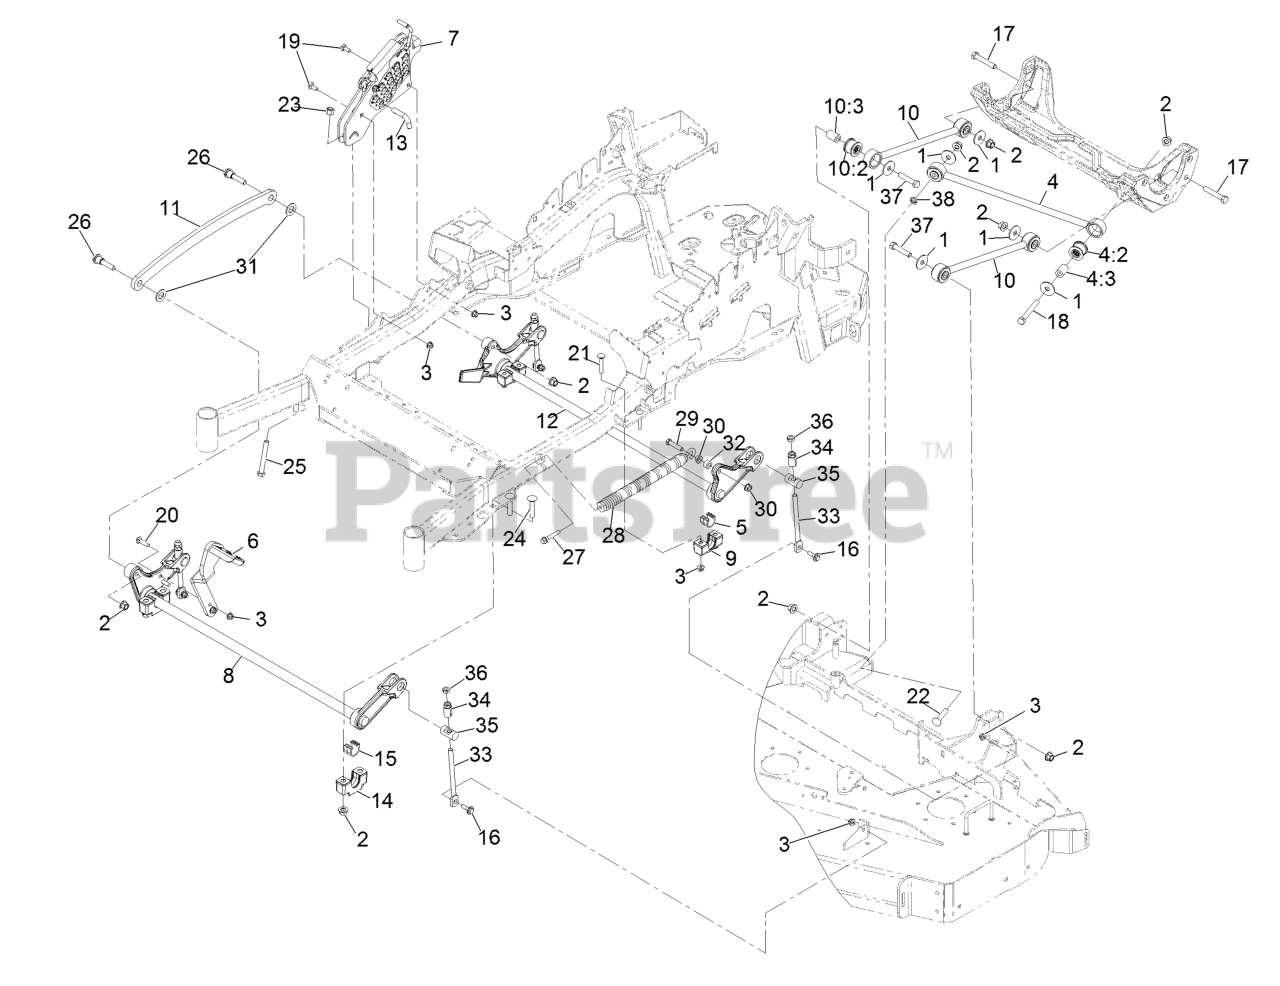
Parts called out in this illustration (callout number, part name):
2	Nut-Lock 1/2-13
3	Nut-Nyloc 3/8-16 Flg
4	Panhard Rod ASM
4:2	Bushing-Suspension, Rubber
5	Bearing-Cross Shaft, Rear
6	Lever-Foot
7	HOC ASM
8	Decklift-Front
9	Support-Cross Shaft, Bearing Rear
10	Deck Strut ASM
10:2	Bushing-Suspension, Rubber
11	Link-Lift, Deck
12	Lift-Deck, Rear
13	Pin-HOC
14	Support-Cross Shaft, Bearing
15	Bearing-Cross Shaft, Front
16	Screw-Hex Flange 3/8-16 X .80
17	Screw-HH 1/2-13 X 3
18	Screw-HH 1/2-13 X 4
19	Bolt-Carriage 3/8-16 X 1
20	Bolt-Carriage 3/8-16 X 1 1/2
21	Bolt-Carriage 3/8-16 X 2 1/4
22	Bolt-Carriage 1/2-13 X 2 1/2
23	Nut-Nyloc 1/2-13
24	Bolt-Carriage 1/2-13 X 2 1/2 Spl Neck
25	Bolt-HH 1/2-13 X 4 Tap
26	Screw-Hex Flange 1/2-13 X 1.90
27	Screw-Shcs 3/8-16 X 2.212
28	Spring-Extension
29	Screw-HH 7/16-14 X 2
30	Nut-Whizlock 7/16-14
31	Washer-3/4 SAE
33	Link-Adjuster, Deck Lift
34	Adjuster-Lift, Deck
35	Trunnion
36	Nut-Jam 1/2-13
37	Screw-HH 1/2-13 X 2 1/2
38	Nut-Push
